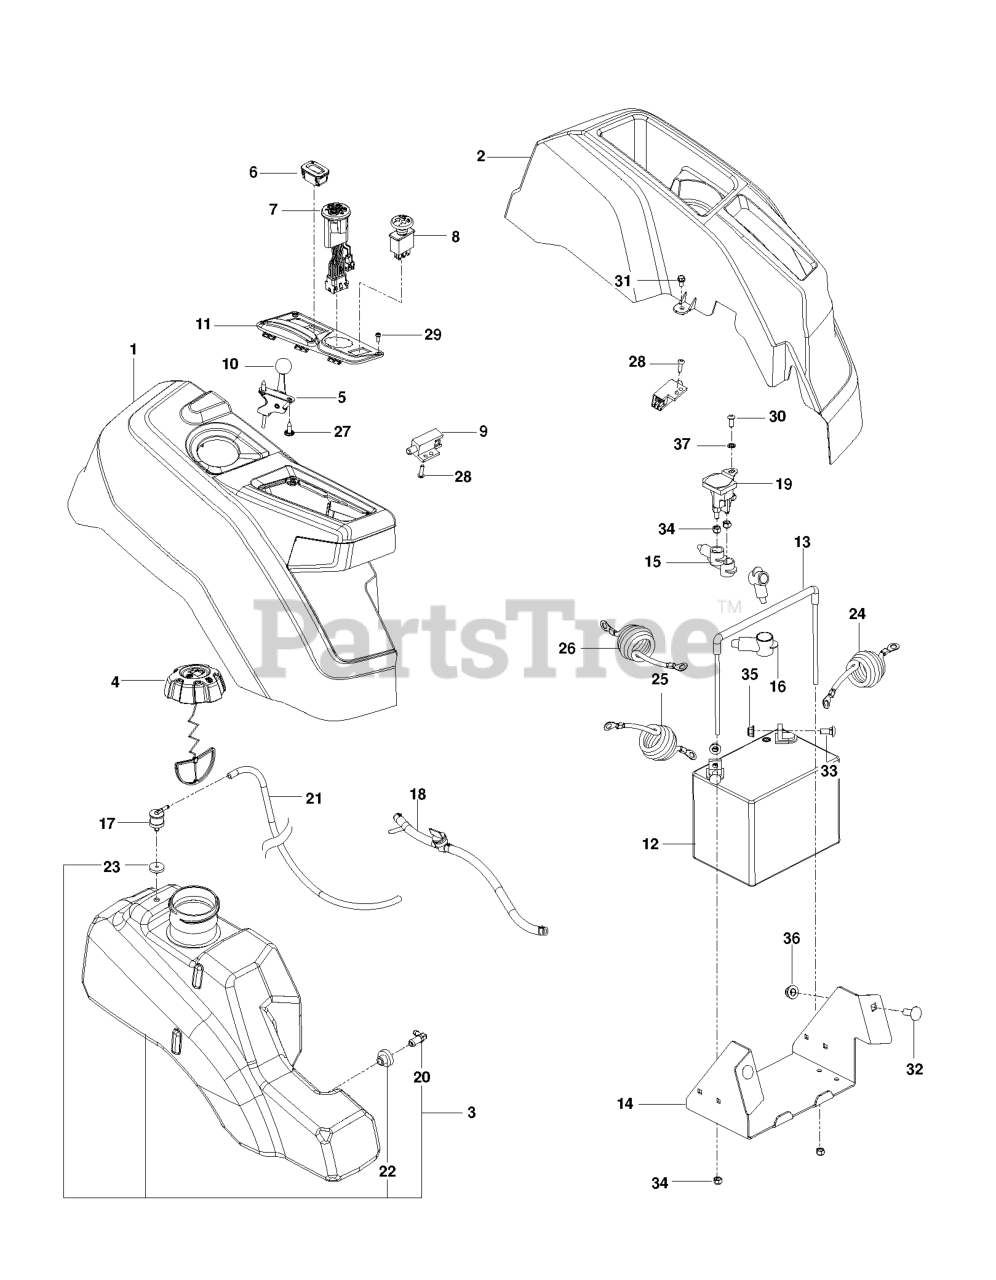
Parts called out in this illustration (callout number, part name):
1	CONSOLE.ASSY.RZ.REFRESH.RH
2	CONSOLE.LH.ASM
3	ASM.FUEL.TANK.LG.3".W/O SHIELD
4	CAP ASSY FUEL 3" GRAY
5	CABLE.THROTTLE.37"
6	GUAGE.SRVCMNDR.HRMTR.
7	SWITCH.ASM.SMARTSWTCH.MY15.ZTR
8	RP SWITCH.PTO.8.TERMINAL.RED
9	SWITCH INTERLOCKT
10	KNOB.ROUND.BALL.BLACK
11	CONTROL.PANEL.RZ.REFRESH.RH
12	BATTERY, 12 V 330 AMP
13	BATTERY TIE DOWN ASSEMBLY
14	BOX BATTERY RZ BLACK
15	TERMINAL COVER
17	VALVE.FUEL.CHECK
18	FUEL.HOSE.SHUT.OFF.ASM.10".3"
19	SOLENOID.W/BRASS.PLUNGER
20	STEM FUEL TANK
21	HOSE 3/16 VAPOR 24"
22	BUSHING OUTLET T
23	GROMMET.ROV.SENTEC
24	CABLE BATTERY POS RZ
25	CABLE.BATTERY.NEGATIVE.RZ
26	CABLE BATTERY POS HARNESS
27	SCREW.PAN.HEAD.#10
28	SCR #10-24 X .75 SKT HD BLK
29	SCREW 6-19X.437
30	SCR 1/4-20 X 5/8 BTN SKT HD ZD
31	SCREW
32	RHSNB 3/8C X 1
33	RP BOLT 5/16-18 X3/4 ZN/YEL GR
34	LOCKNUT.NYLOC.1/4-20
35	5/16-18 NYLOC FLANGE NUT
36	NUT 3/8-16 HEX FLG NYLOC ZD
37	WASHER 1/4 INT TOOTH
